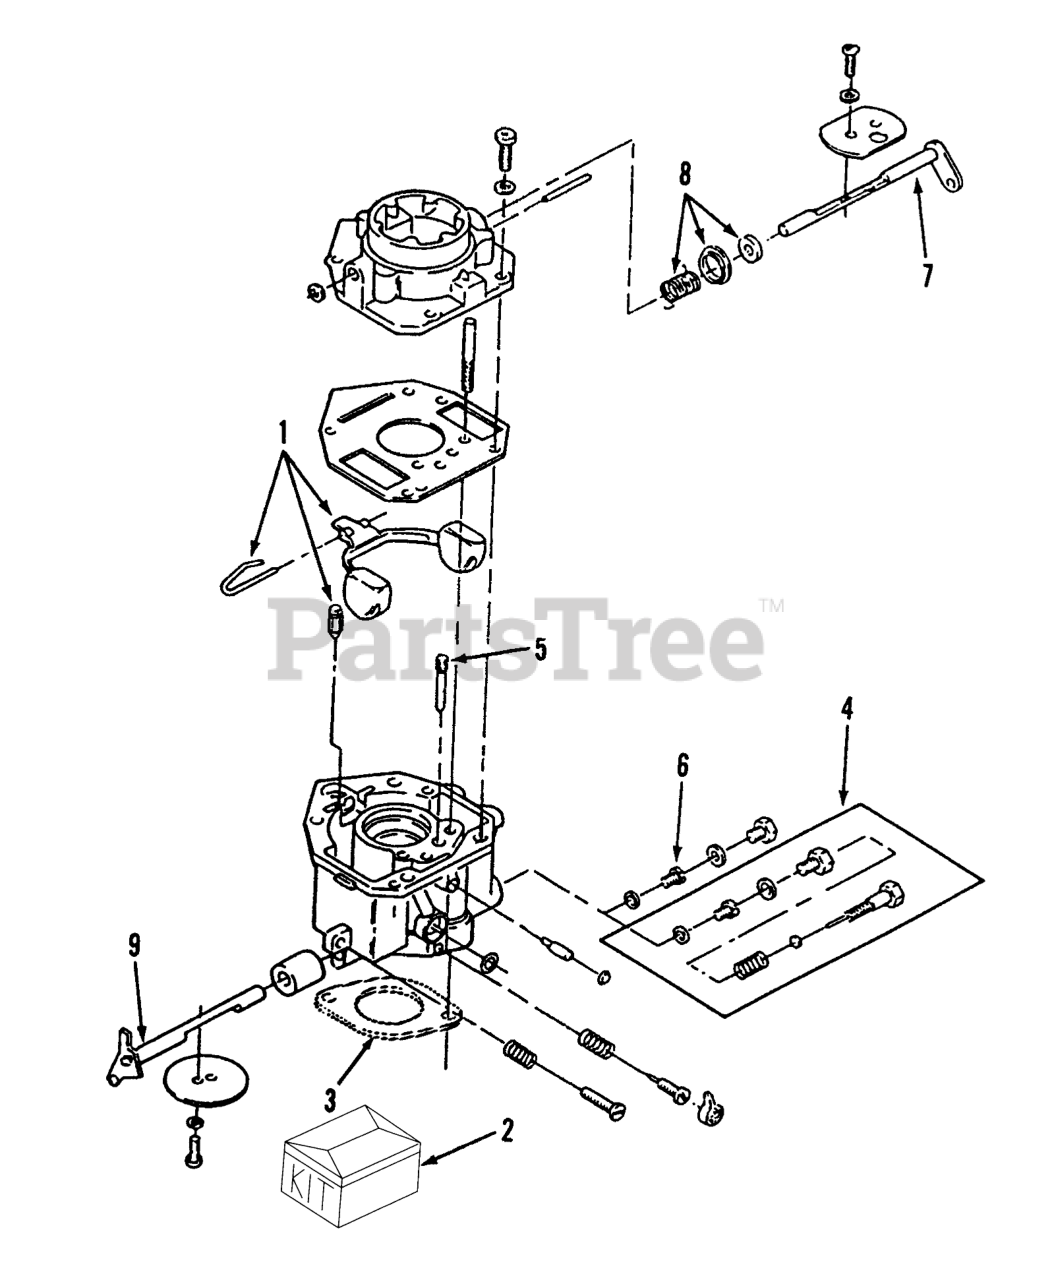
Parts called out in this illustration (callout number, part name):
1	Kit-Float (Includes Float, Pin, & Valve)
2	Kit-Repair (Includes Screw & Plug Package, Gasket Package, Float Valve, Idle Adjust Needle & Spring, Mounting Gaskets, & Idle Limit Cap)
3	Oil Fill Tube
4	FIXED-JET
5	IDLE-JET
6	POWER JET
7	Kit-Shaft, Choke (Includes Choke Valve, Valve Setscrew, & Air Filter)
8	Kit-Lever, Choke (Includes Choke Lever Ring, Choke Spring, & Choke Collar)
9	Kit-Shaft, Throttle (Includes Valve Setscrew, Air Filter, & Throttle Valve)
